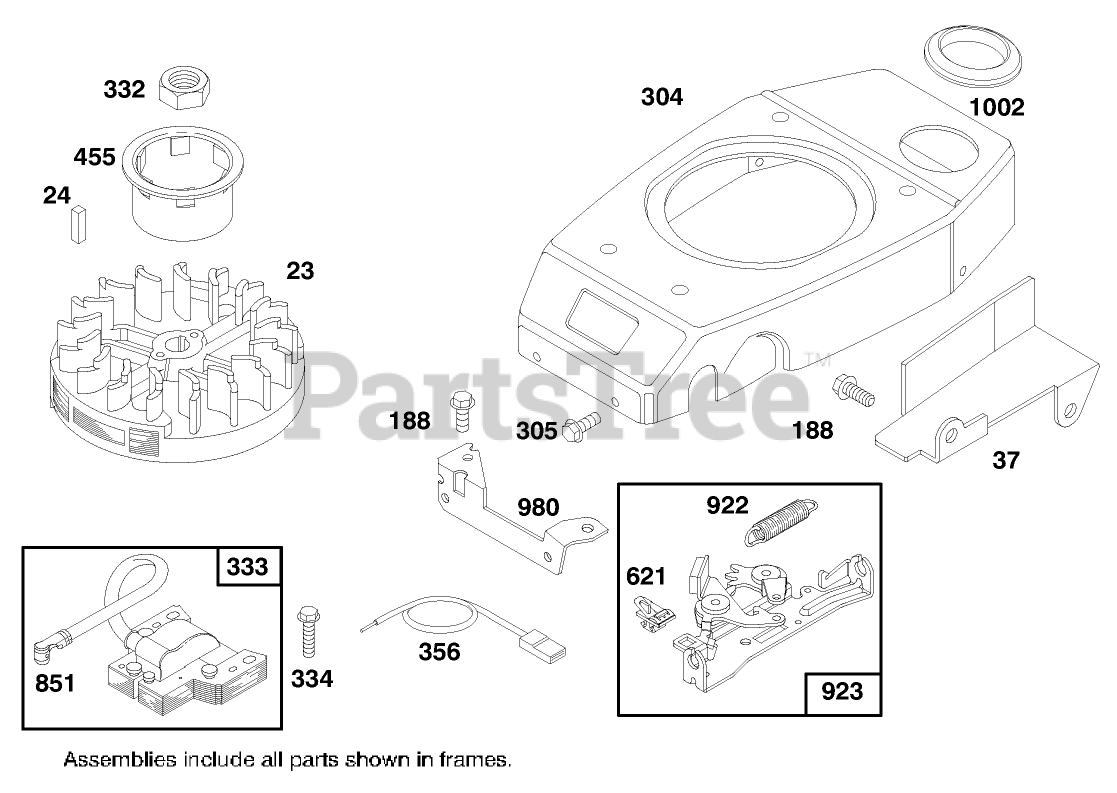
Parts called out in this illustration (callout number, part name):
24	KEY - FLYWHEEL
37	GUARD - FLYWHEEL
304	HOUSING - BLOWER
305	SCREW - HEX HEAD
332	NUT - HEXAGON
356	WIRE - GROUND
621	STOP SWITCH
980	BRACKET-BLOWER HSG
